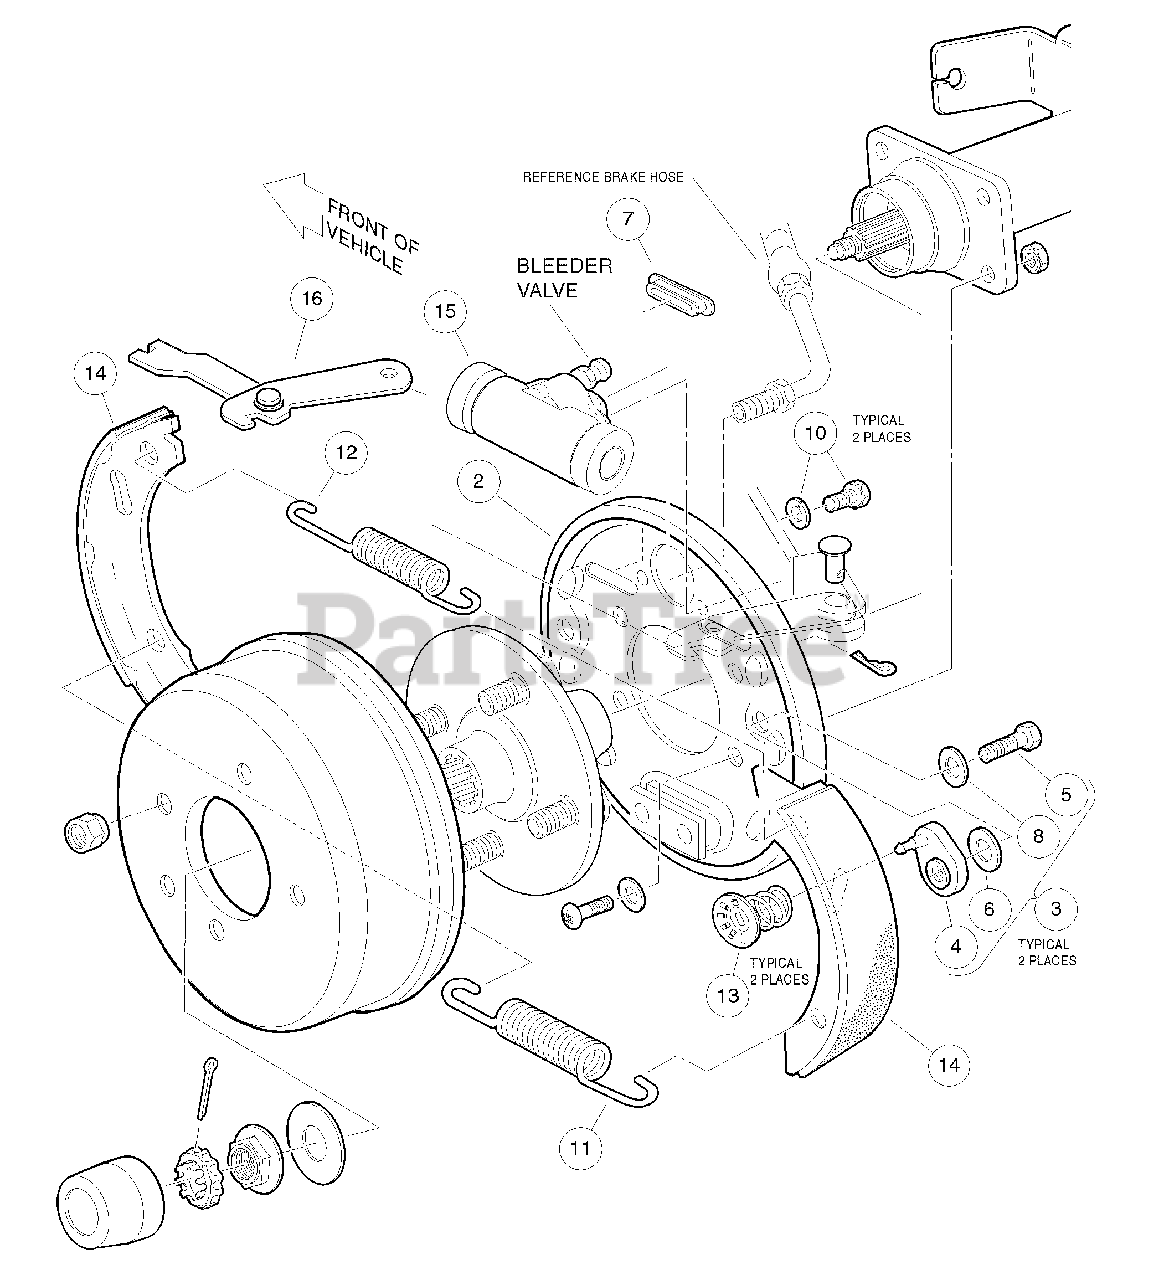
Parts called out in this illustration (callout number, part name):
1	Assembly, Brake Cluster LH
2	Backing Plate Asm
3	Kit, Axle Adjuster
5	Bolt, 1/4-28 UNF X 31
7	Dust Cover
8	Washer, 1/4 Flat
9	Kit, Axle Hardware
10	Bolt, Wheel Cylinder
11	Spring, Shoe To Shoe, Lower
12	Spring, Shoe To Shoe, Upper
13	Shoe Hold Down
14	Shoe Kit, Axle Set
15	Wheel Cylinder Assembly 0875 Dia
16	Park Brake Assembly, Left-Hand
17	Assembly, Brake Cluster RH
18	Backing Plate Asm
19	Kit, Axle Adjuster
21	Bolt, 1/4-28 UNF X 31
23	Dust Cover
24	Washer, 1/4 Flat
25	Kit, Axle Hardware
26	Bolt, Wheel Cylinder
27	Spring, Shoe To Shoe, Lower
28	Spring, Shoe To Shoe, Upper
29	Shoe Hold Down
30	Shoe Kit, Axle Set
31	Wheel Cylinder Assembly 0875 Dia
32	Park Brake Assembly, Right-Hand
